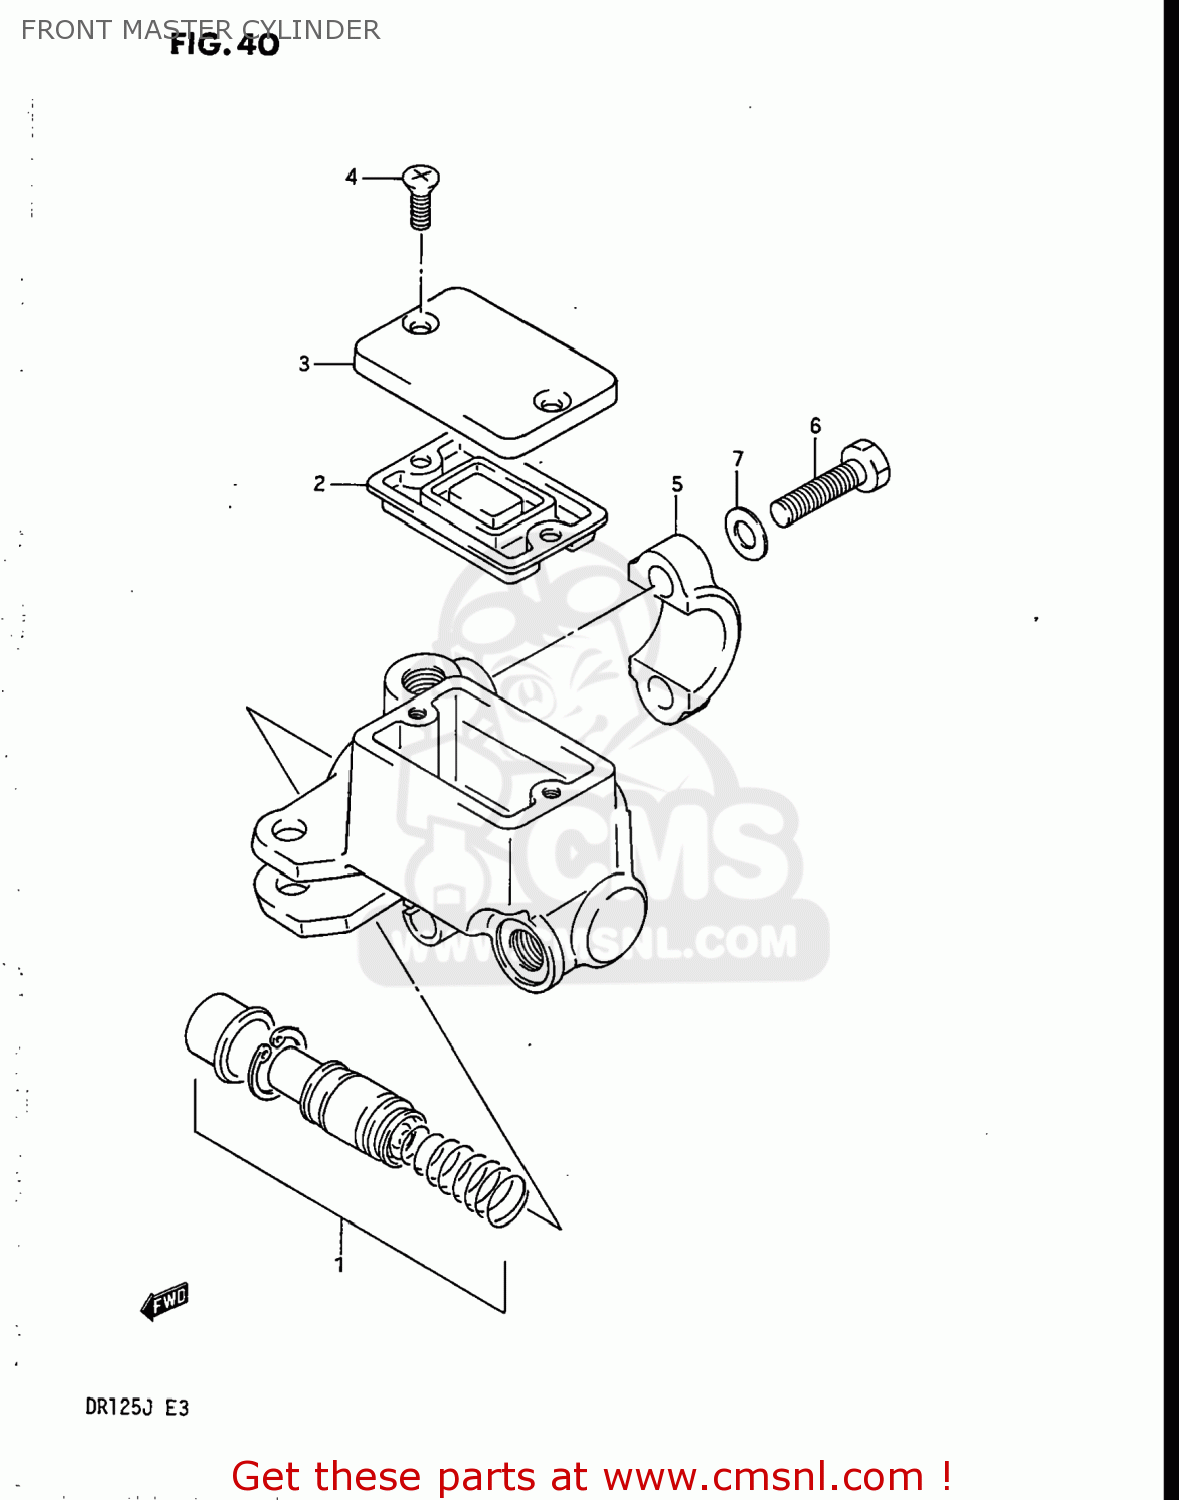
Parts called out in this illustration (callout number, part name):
1	PISTON/CUP SET
2	DIAPHRAGM
3	CAP
4	SCREW
5	HOLDER
6	BOLT
7	WASHER
